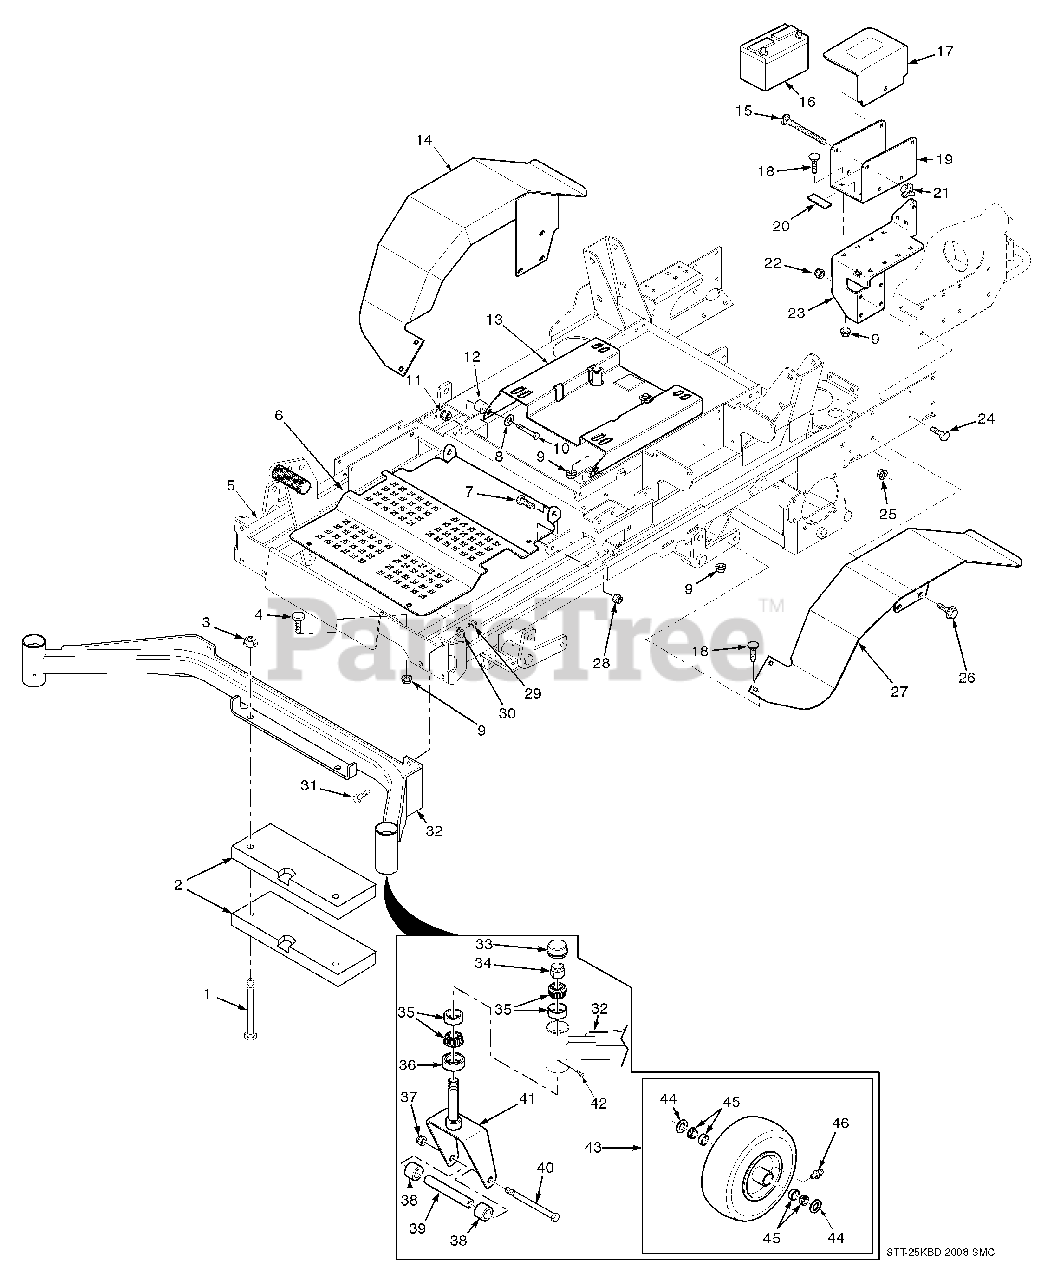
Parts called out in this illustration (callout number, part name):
1	Bolt, Hex Head 1/2-13 x 3.5”
2	Weight
3	Nut, Hex Elastic Stop 1/2-13
4	Bumper, Rubber 5/16-18 x 5/8”
5	Main Frame Assembly w/Decals
6	Foot Plate
7	Bolt, Hex Head 3/8-16 x 1”
8	Flatwasher, 3/8-.391 x .938 x .105
9	Nut, Hex Serrated Flange 5/16-18
10	Bolt, Hex Head 3/8-16 x 2.0”
11	Nut, Elastic Stop 3/8-16
12	Spacer Bushing
13	Seat Plate Weldment w/Decal
14	Fender Weldment, RH
15	Bolt, Carriage 1/4-20 x 6”
16	Battery
17	Cover, Battery
18	Bolt, Carriage 5/16-18 x 3/4”
19	Plate, Battery Box
20	Rubber Pad
21	Wing Nut, 1/4-20 x 3/4”
22	Nut, Elastic Stop 3/8-16
23	Battery Box Mount
24	Bolt, Hex Head 3/8-16 x 1”
25	Nut, Hex Serrated Flange 3/8-16
26	Screw, Hex Serrated Flange 3/8-16 x 1”
27	Fender Weldment, LH
28	Nut, Hex Elastic Stop 3/8-16
29	Nut, Elastic Stop 7/16-14
30	Lockwasher, 7/16”
31	Bolt, Hex Head 7/16-14 x 1-1/4”
32	Extention Weldment, Caster
33	Cap, Grease
34	Nut, Hex Elastic Stop 1.0”-14
35	Bearing W/Race
36	Seal, 2.00” OD. x 1.625” Bore
37	Nut, Hex Elastic Stop 1/2-13
38	Spacer, Caster Wheel
42	Plug, 1/4-28 THD Form
43	Wheel Assembly
45	Bearing w/ Race
46	Grease Fitting
